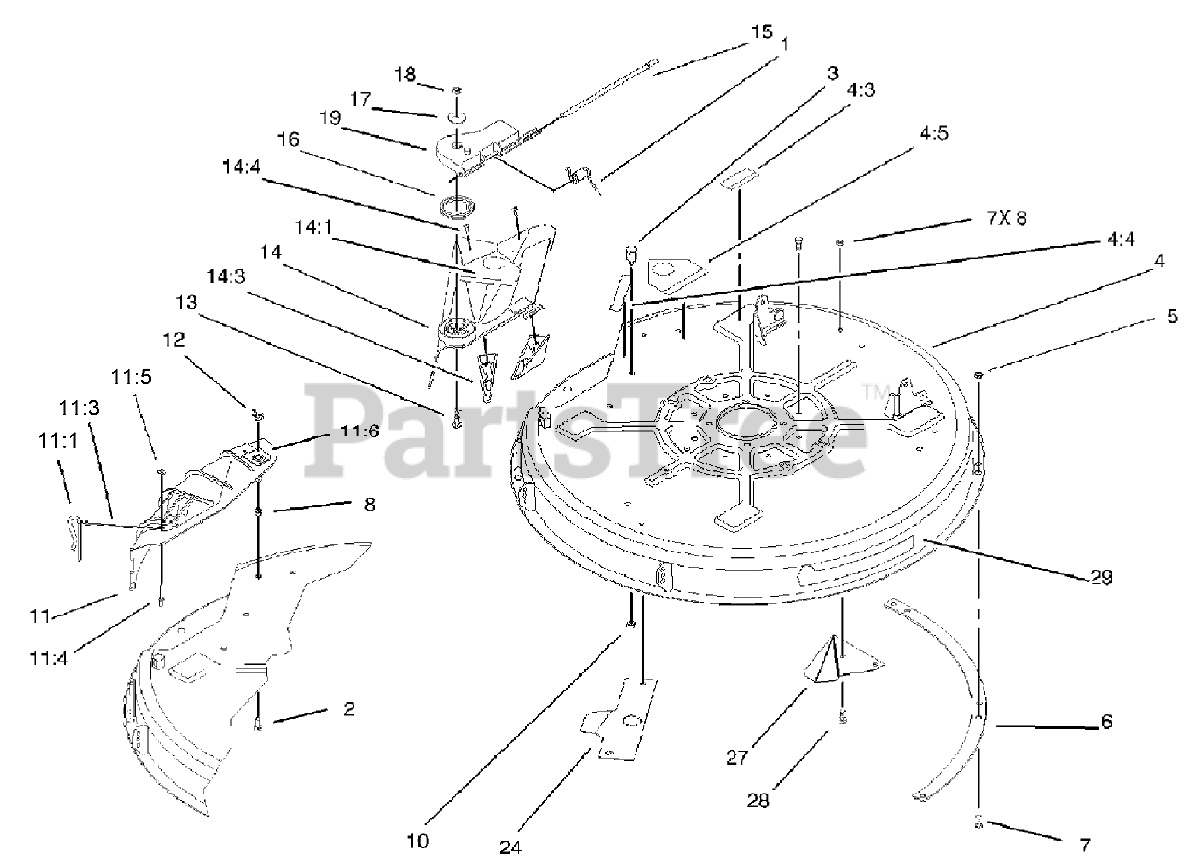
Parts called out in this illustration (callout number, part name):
1	SPRING-TORSION
2	SCREW-HH
3	POST-PIVOT
4	DECK ASM
4:3	DECAL-WARNING
4:4	DECAL-DANGER
4:5	DECAL-DANGER
5	NUT-LOCK, NI
6	RING-DECK
7	SCREW-HH
8	NUT-LOCK, NI
10	NUT-LOCK, NI
11	DISCHARGE COVER ASM
11:1	PIN-LOCKING, CHUTE
11:3	LANYARD
11:4	RIVET-BLIND
11:5	WASHER-PLAIN
12	NUT-WING
13	BOLT-SHOULDER
14	32 INCH DEFLECTOR ASM
14:1	DECAL-DANGER
14:3	KICKER
14:4	SCREW-PPH
15	ROD-HINGE, DEFLECTOR
16	SPRING-TORSION
17	WASHER-FLAT
18	NUT-LOCK, NI
19	PIVOT-HINGE, DEFLECTOR
24	RAMP-DEFLECTOR
28	SCREW-HH
29	DECAL-RECYCLER
